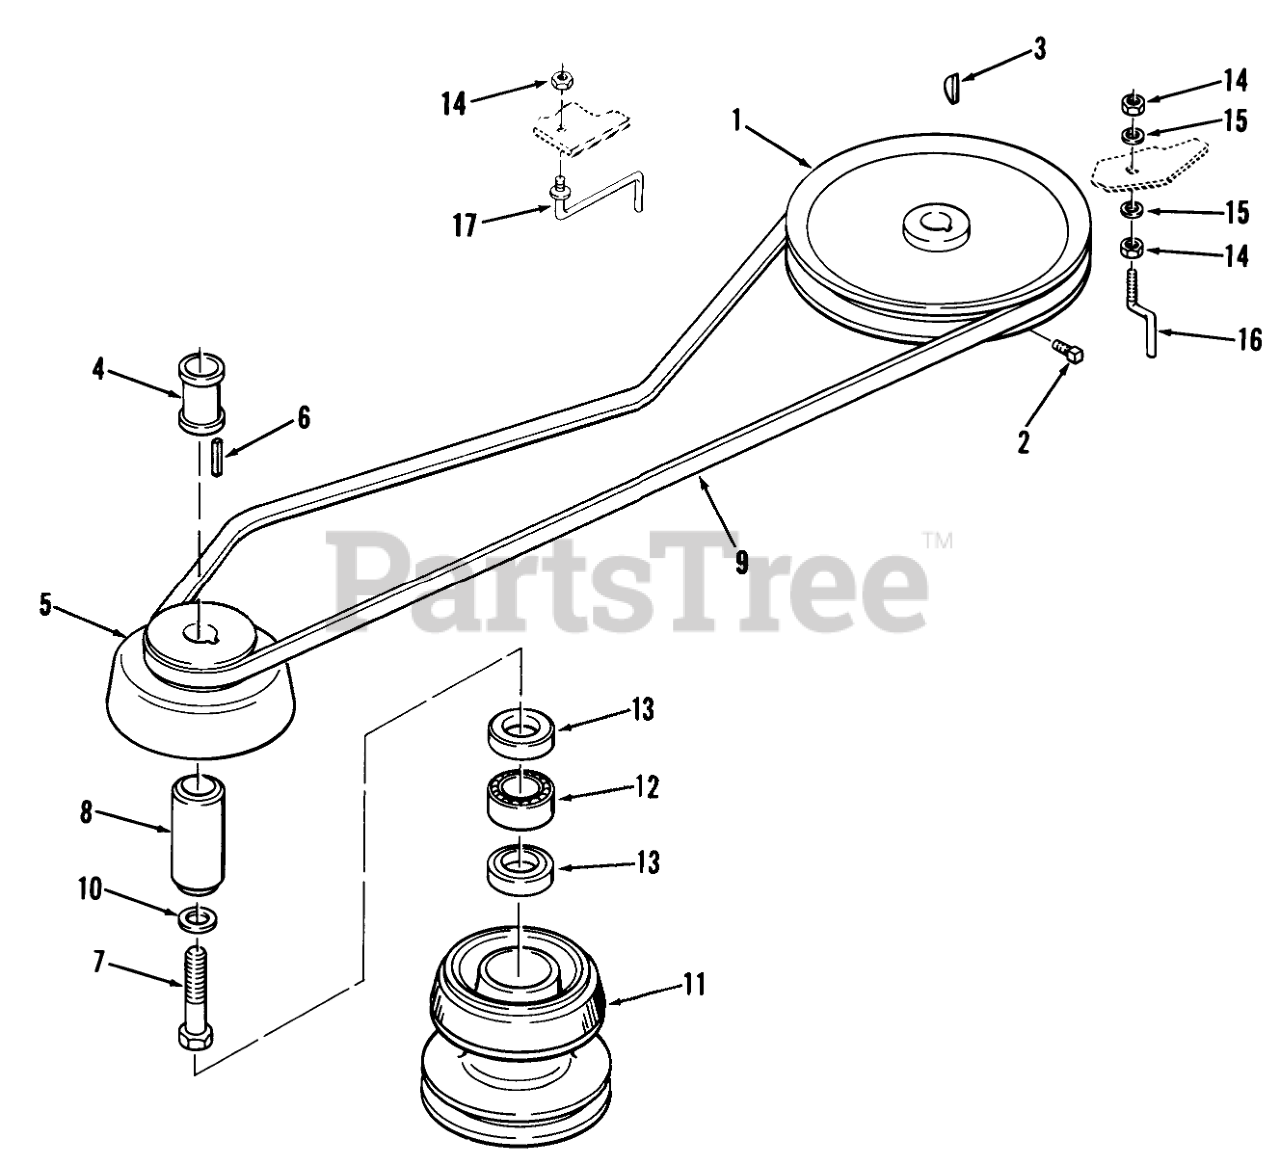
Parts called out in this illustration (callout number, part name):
1	PULLEY-TRANS
1	PULLEY-TRANSMISSION
2	Set Screw
3	KEY-HI-PRO
3	HARD HI PRO KEY
4	TUBE SPACER
4	Tube Spacer LT-1032 Only
5	PULLEY-ENGINE
5	Pulley Engine LT-1032 Only
6	Key 3/16 x 3/16 x 5/8
7	HEX HD CAP SCREW
7	Bolt 3/8-16 x 3 1/4
8	RACE BEARING
8	Bearing Race LT-1032 Only
9	V-BELT
10	WASHER
11	Assy Pulley Mwr Dr
12	BRG-NEEDLE OPEN END
13	SEAL-OIL
14	Nut
15	WASHER 5/16 SAE
16	GUIDE-BELT
17	GUIDE-BELT
